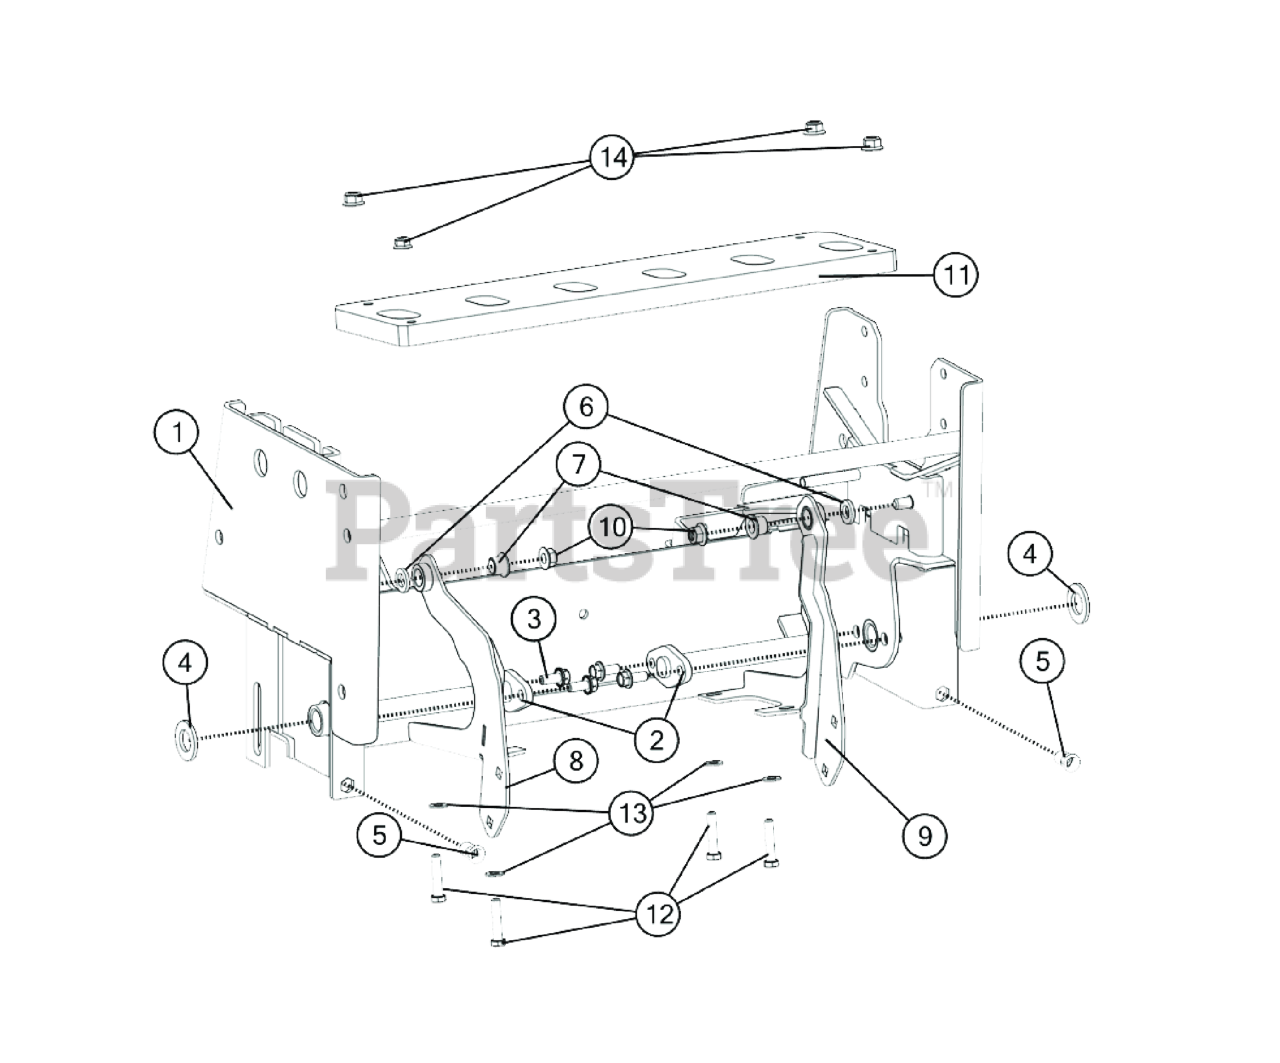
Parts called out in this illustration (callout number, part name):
1	ASM, PAINTED SUB-FRAME W/ INSERTS
2	WA, AXLE REAR
3	SER HEX WASHER FLNG SCREW 5/16"-18 X 3/4"
4	WASHER 3/4" SAE 13/16"X1.5"X1/8"ZP
5	NUT INSERT HEX 5/16"-18, .150-.312 GRIP RANGE
6	WSHR-NYL, FLT, .500" X .875" X .125"
7	BUSHING .500" ID
8	WA, TINE GATE ARM RH
9	WA, TINE GATE ARM LH
10	NUT-HEX-NYLK, FLG .375"-16 ZP
11	GATE, 6 TINE
12	SCREWCAP 5/16"-18X1 1/2" HCS ZP
13	WASHER 5/16" SAE Z/P
14	NUT-HEX-NYLK, FLG .3125-18 ZP
